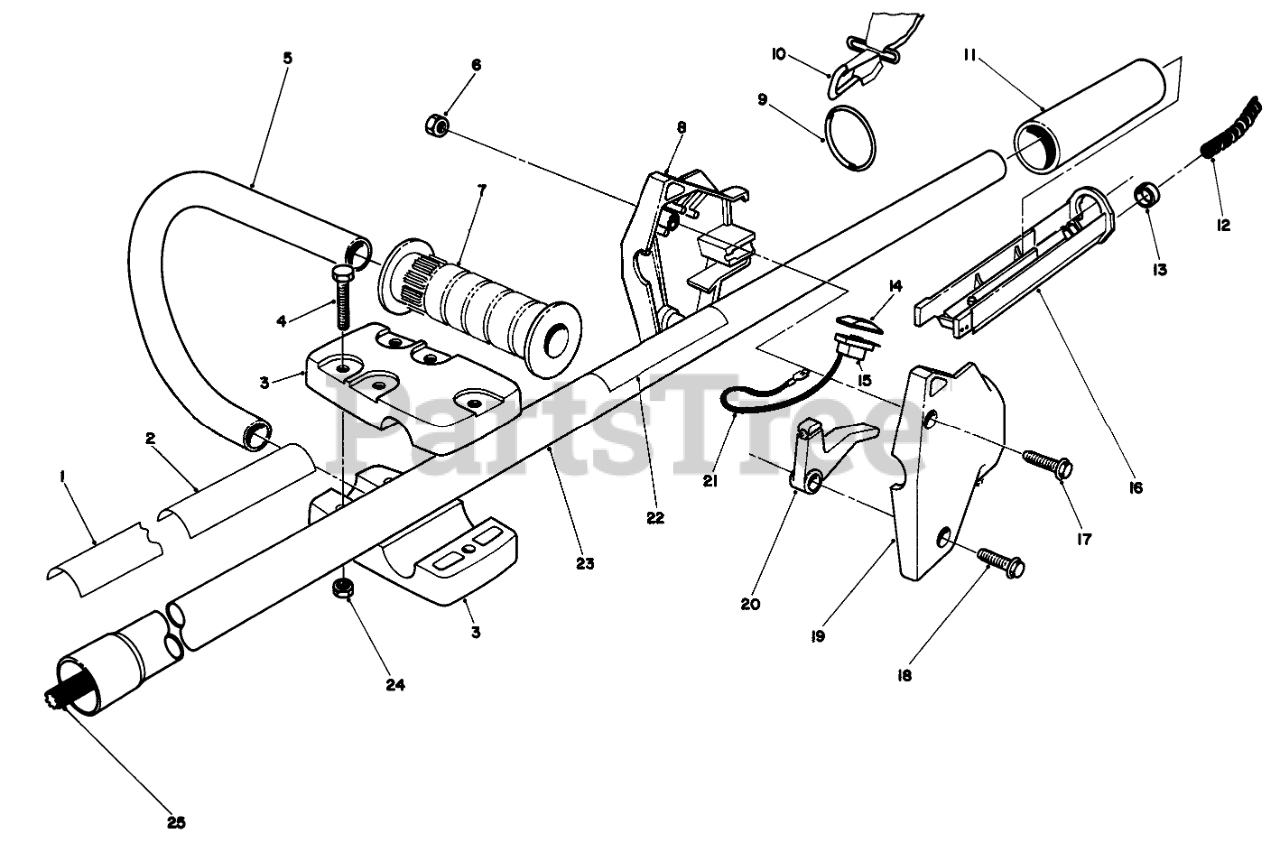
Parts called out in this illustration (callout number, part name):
1	DECAL - TC3500
2	DECAL-INSTRUCTION
3	CLAMP
4	SCREW-HH
5	J HANDLE TUBE
6	NUT-LOCK, NI
7	LH GRIP
8	THROTTLE HSG.R H
9	RING-HARNESS
10	Harness-Shoulder
11	GRIP - RUBBER
12	CABLE COVER
13	RING FITTING
14	SWITCH COVER-BLACK
15	SWITCH
16	TROUGH 1"
18	SCREW-HWH
19	THROTTLE HSG. L H
20	THROTTLE LEVER
21	WIRE ASM
22	Decal Danger
23	TUBE ASSEMBLY
24	NUT-LOCK, NI
25	SPLINE SHAFT
